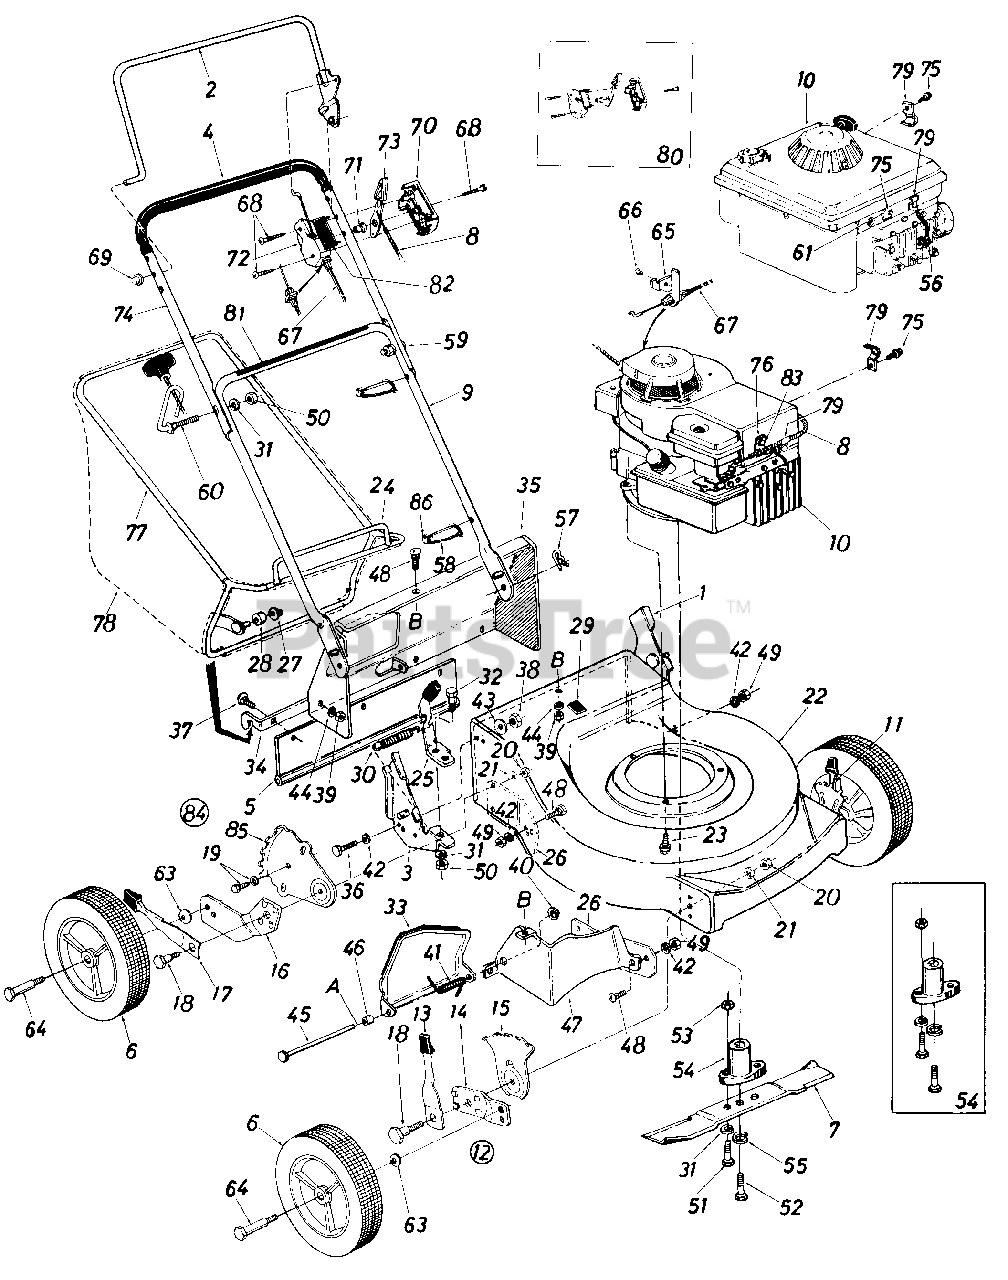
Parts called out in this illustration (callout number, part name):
1	Handle Brkt. Ass'y.-L.H.
2	Control Handle Ass'y.-L.H.
3	Handle Brkt. Ass'y.-R.H.
5	Rear Flap Ass'y.
6	Wheel Ass'y.
7	21" Blade
8	Throttle Wire-58" (Black)
9	Lower Handle (Chrome)
10	Engine
11	Front L.H. Height Adj. Ass'y.
12	Front R.H. Height Adj. Ass'y.
13	Spring Lever Ass'y. w/Knob
14	Front Pivot Bar
15	Front Index Plate
16	Rear Pivot Bar-R.H.
17	Spring Lever w/Knob
18	Shld. Bolt .50" Dia. x .375
19	Hex Wash. Hd. Tap Scr. 1/4 x.62" Lg.
20	Hex Nut 3/8-16 Thd.*
21	Bell-Wash. .39" I.D. x .38"
26	Baffle
27	Push Nut 3/8" Rod
28	Plastic Roller
29	Plug-Catcher Hook Slot
30	Tension Spring
31	L-Wash. 5/16" I.D.
32	Shld. Bolt .437" Dia. x .162
33	Chute Door
34	Grass Catcher Hitch Brkt.
35	Rear Discharge Deck Section
36	Hex Bolt 1/4-28 x .75" Lg.
37	Carr. Bolt 1/4-20 x .75" Lg.
38	Hex Nut 1/4-28 Thd.
39	Sems Nut 1/4-20 Thd.
40	Push Nut 1/4" Rod
41	Torsion Spring
42	L-Wash. 1/4" I.D.
43	Bell-Wash. 1/4" I.D. x .88"
44	Fl-Wash. .285" I.D. x 1.25"
45	Hinge Pin .250" Dia. x 7.25"
46	Spacer .262" I.D. x .31 " O.D. x .58
47	Rear Baffle
48	Carriage Bolt 1/4-20 x .50"*
49	Hex Nut 1/4-20 Thd.*
50	Hex Nut 5/16-18 Thd.*
51	Hex Bolt 5/16-24 x 1.00" Lg. (Grade 5)
52	Hex Bolt 3/8-24 x 2.25" Lg. (Grade 5)
53	Hex Nut 5/16-24 Thd.*
54	Blade Adapter Kit
55	L-Wash. 3/8" I.D.-H.D.
56	Spark Plug Boot
57	Intern. Cot. Pin 5/16" Dia.
58	Cable Tie
59	Curved Carriage Bolt 5/16-18 x 1.38" Lg.
60	Rope Guide Bolt
61	Casing Clamp
63	Bell-Wash. .400" I.D. x .88" O.D. x .060
64	Axle Bolt
65	Cable Bracket
66	Pop Rivet .156" Dia. x .379
67	Brake Control Cable-43"
68	Truss Mach. Hd. "B" Tap Scr. #12 x 1.50" Lg.
69	Cap Speed Nut 5/16" Rod
70	Control Panel Half
71	Control Disc Pin
72	Clutch Panel Half
73	Throttle Control Lever
74	Upper Handle (Chrome)
75	Hex "B" Tap Scr. #10 x .38"
76	Casing Clamp
77	Grass Catcher Upper Frame
78	Grass Bag (Without Flip Top)
79	Casing Clamp
80	Control Housing Comp.
81	Instruction Label-Handle
82	Control Label-Throttle
83	Hex Wash. Hd. AB-Tap Scr. #8 x .38" Lg.
84	Rear Height Adj. Ass'y.-R.H.
85	Rear Index Plate
86	Cable Anchor
